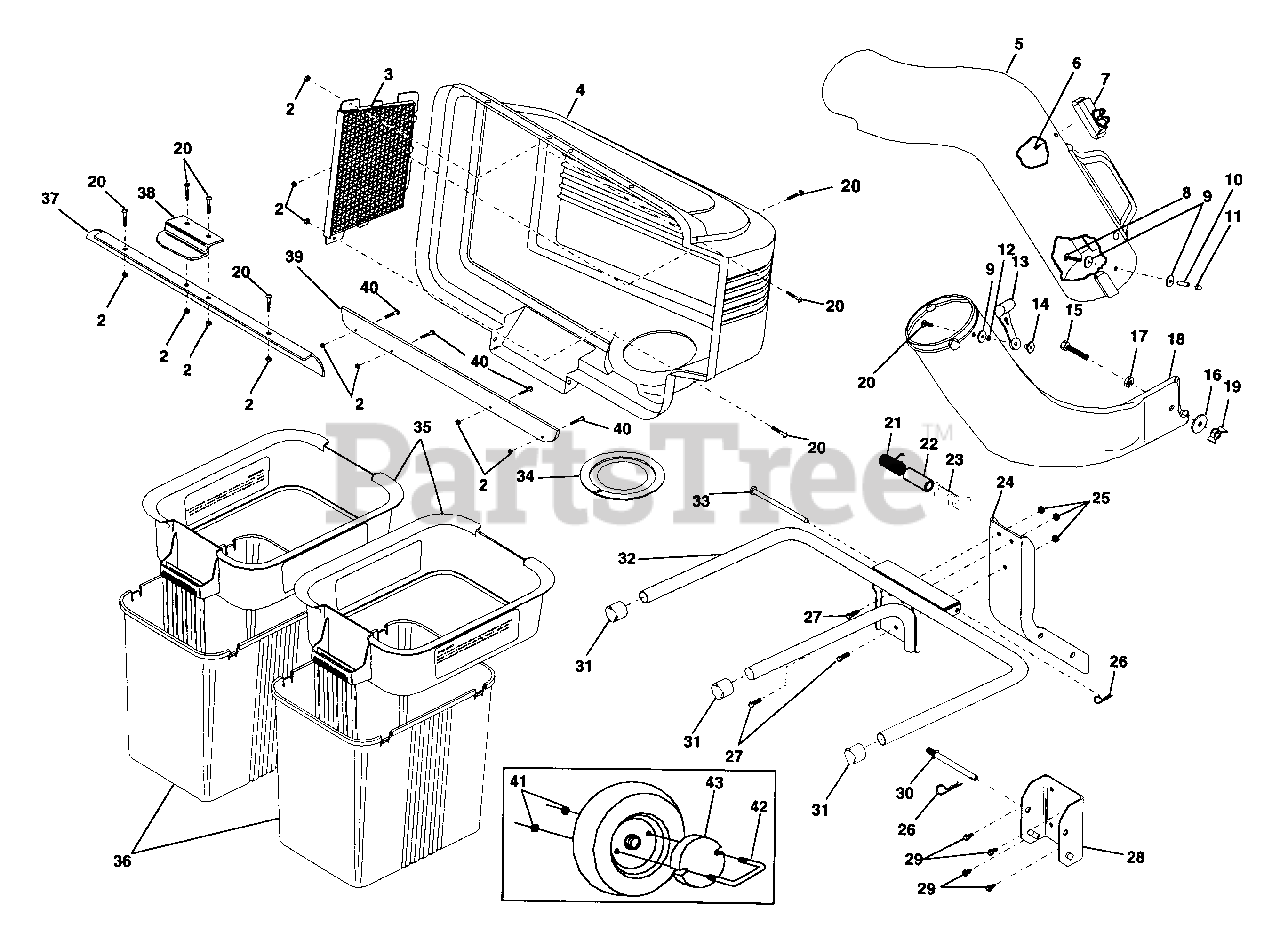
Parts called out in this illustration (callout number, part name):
2	Nut, Crownlock #10-24
3	Screen, Cover
4	Cover
5	Chute, Upper
6	Screw, Special #10-14 x 1/2
7	Dump Bag Indicator
8	Screw, #10-24 x 1-1/8
9	Washer 3/16 x 3/4 x 16 Ga.
10	Spacer, Split
11	Nut, Acorn #10-24
12	Washer, lock
13	Latch, Chute
14	Nut, Weld
15	Bolt, Hex 3/8-16 x 1-1/4
16	Washer 13/32 x 1 x 16 Ga.
17	Locknut 3/8-16
18	Chute, Lower
19	Wingnut 3/8-16
20	Screw #10-24 x 5/8
21	Spring, Cover L.H. (black)
22	Spacer, Cover
23	Spring, Cover R.H. (gray)
24	Post, Support
25	Locknut 5/16 x 18
26	Spring, Retainer
27	Bolt, Hex 5/16-18 x 3/4
28	Bracket, Mounting
29	Screw 5/16-18 x 1/2 Hex, Self Tapping
30	Pin, Support Post
31	Plug, Tubing End
32	Bagger, Frame
33	Pin, Hinge
34	Gasket, Cover
35	Container, Top
36	Container, Bottom
37	Seal, Cover
38	Latch Handle, Cover
39	Strip, Seal
40	Screw #10-24 x 1/2
41	Locknut 3/8-16
43	Wheel Weight
